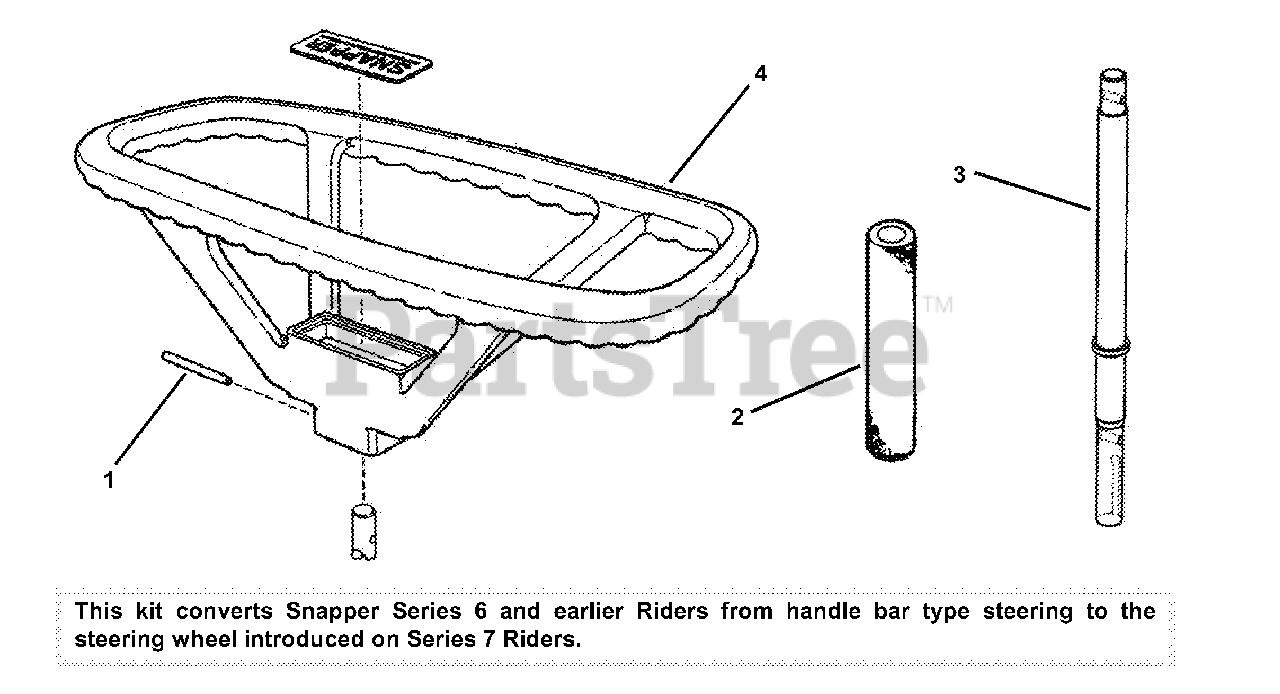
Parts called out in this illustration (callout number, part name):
1	PIN, 1/4 x 1-3/4" Roll
2	FOAM COVER, Steering Shaft
3	WELDMENT, Conversion Rod
4	ASSEMBLY, Steering Wheel
